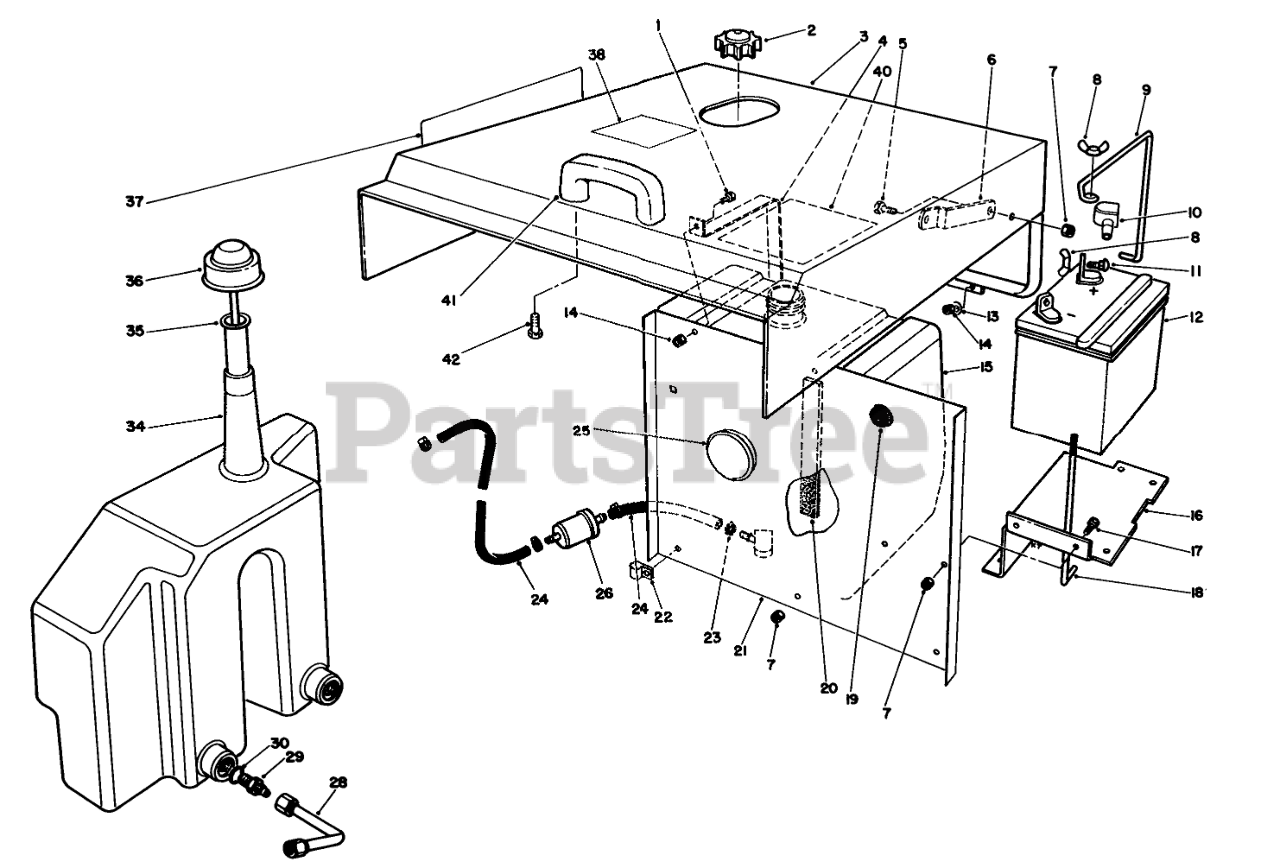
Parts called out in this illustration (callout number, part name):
1	SCREW-HH
2	GAS CAP ASM
3	HOOD-118 - SERVICE
4	Strap-Fuel Tank
5	SCREW-HH
6	UPPER HOOD STOP
7	NUT-LOCK, NI
8	NUT-WING
9	BATTERY CLAMP
10	BOOT-TERMINAL, RED
11	BOLT-CARR
12	Battery
13	WASHER-FLAT
14	NUT-LOCK, NI
15	TANK-FUEL
16	Support-Battery
17	SCREW-HH
18	ROD-SUPPORT, BATTERY
19	GROMMET
20	TANK SPONGE
21	Shield-Heat
23	CLAMP-WORM
24	GAS HOSE
25	PLUG BUTTON CAP
26	FUEL FILTER
28	TUBE ASM
29	Fitting-Hydraulic Straight (Incl. Ref. #30)
30	O-RING
34	OIL RESERVOIR
35	SCREEN-FILLER
36	CAP WA
37	Decal-ProLine 120
38	DECAL - CAUTION FUEL
40	DECAL - SERVICE PL120
41	HANDLE-DOOR
42	SCREW-HWH
